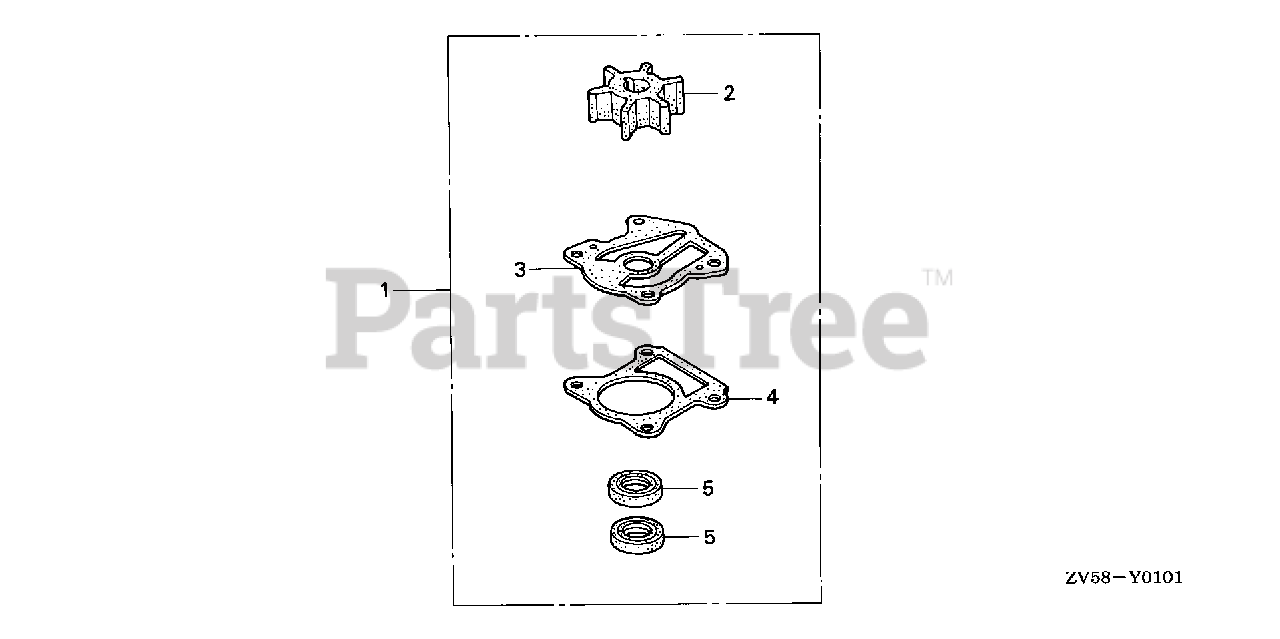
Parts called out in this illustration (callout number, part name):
1	IMPELLER KIT, WATER PUMP (NOT AVAILABLE)
2	IMPELLER, PUMP
3	GASKET B, IMPELLER
4	GASKET, WATER PUMP
5	SEAL, WATER (17X30X7)
